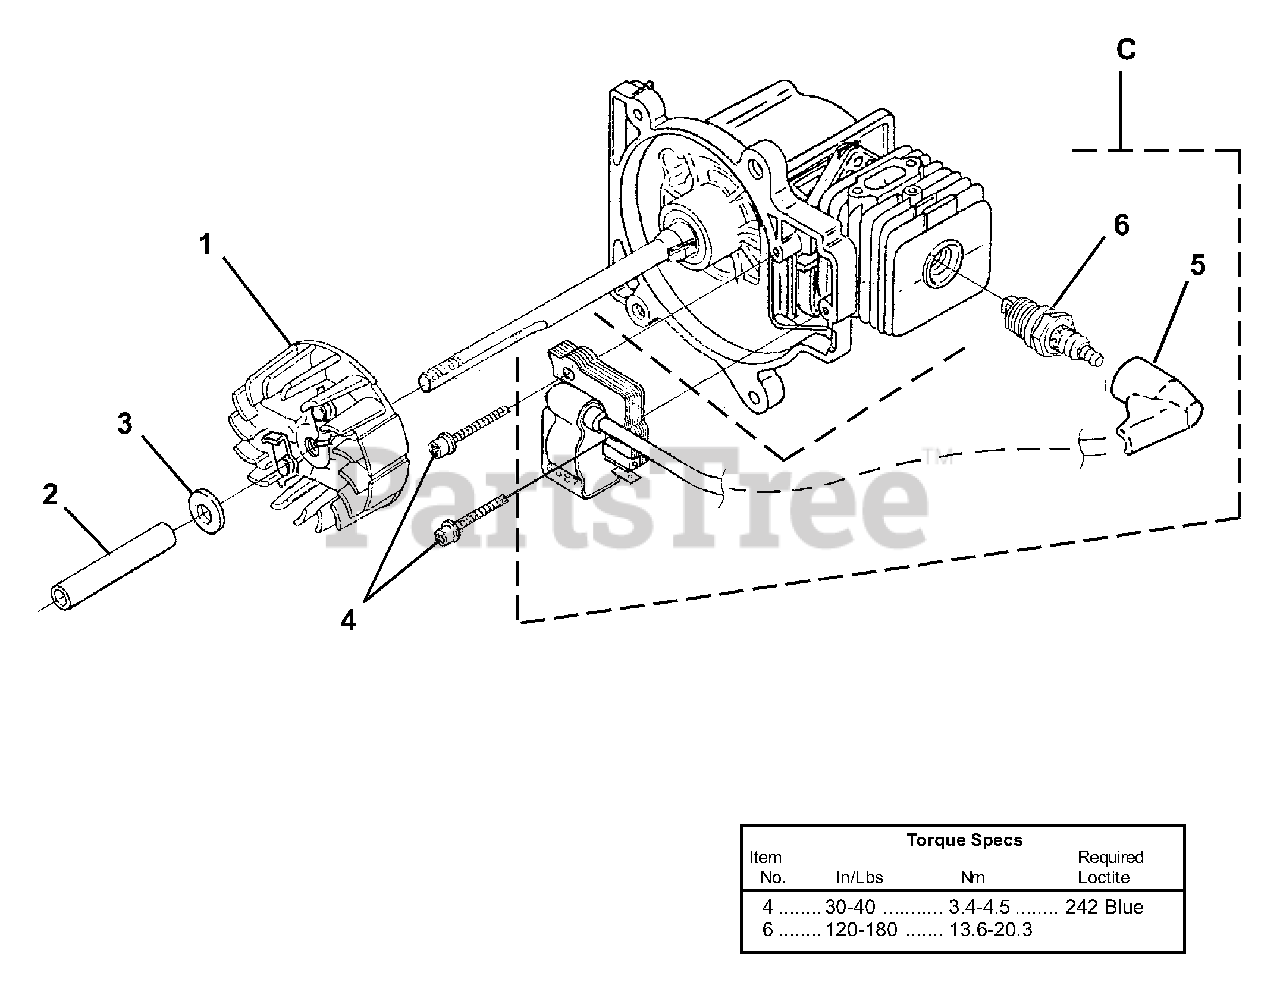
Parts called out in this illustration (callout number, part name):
1	Rotor & Starter Pawls
3	Washer, Flat
4	Screw-Thread Forming (8-32 X 1)
5	Ignition Module
6	Spark Plug
C	Ignition Kit w/Ignition Module
